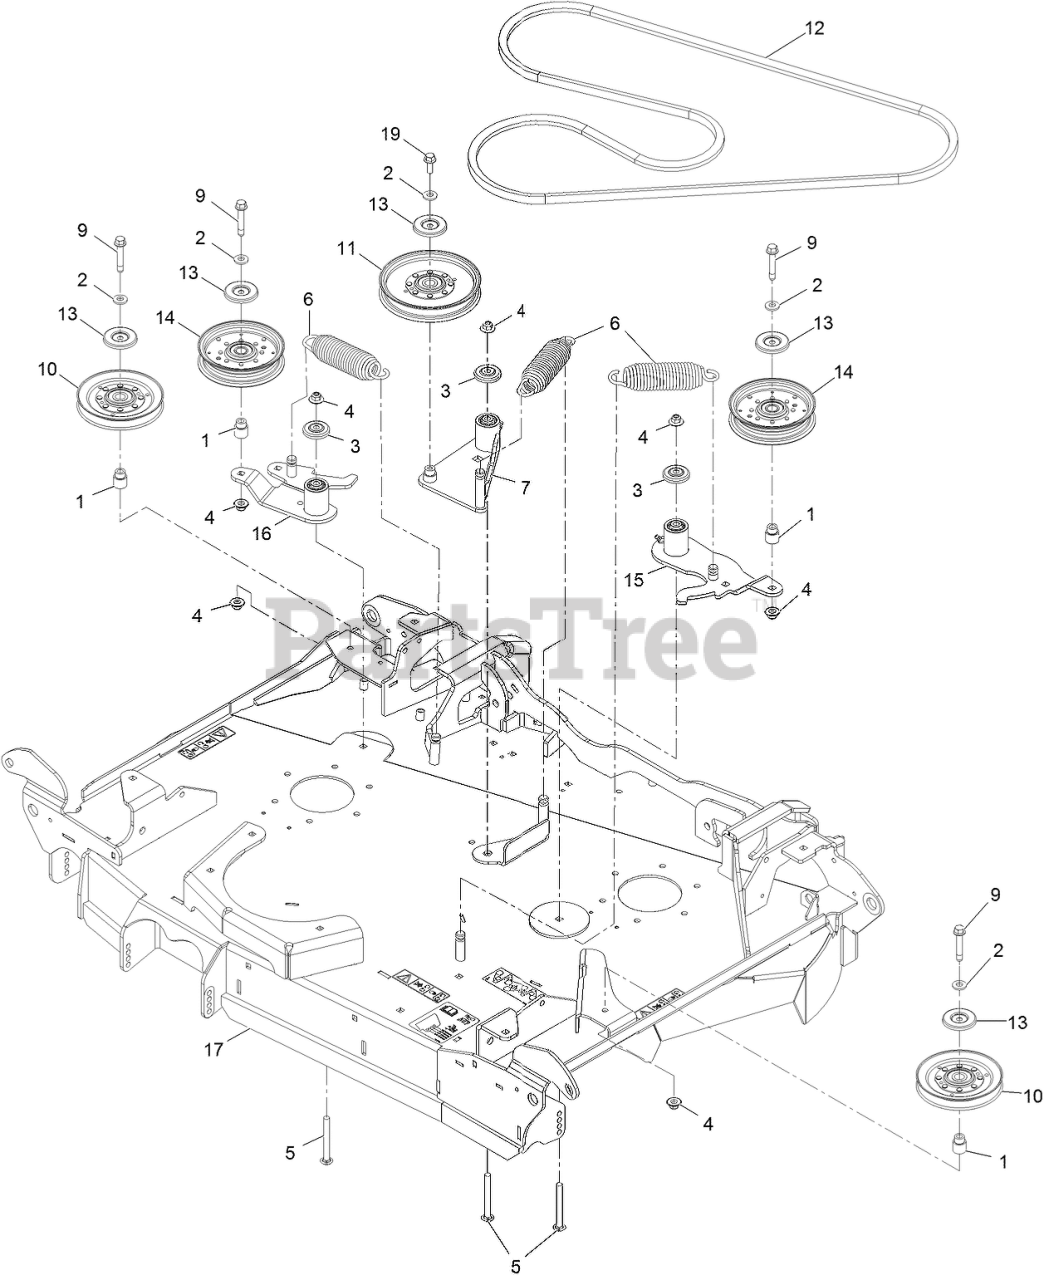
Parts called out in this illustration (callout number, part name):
1	BUSHING-IDLER
2	WASHER-BELLEVILLE
3	GUARD-TOP
4	Nut-Nyloc 3/8-16 Flg
5	BOLT-SHOULDER, CARRIAGE 3/8-16 X 3 1/2
6	SPRING-EXTENSION
7	IDLER ARM ASM
9	SCREW-HHF W/ PATCH
10	IDLER-V
11	IDLER-PULLEY
13	SHIELD-DUST
14	PULLEY-IDLER, FLAT
15	IDLER ASM
16	IDLER ASM
17	ASM-Deck, Ctr 96/120
19	SCREW-HHF 3/8-16 X 1
